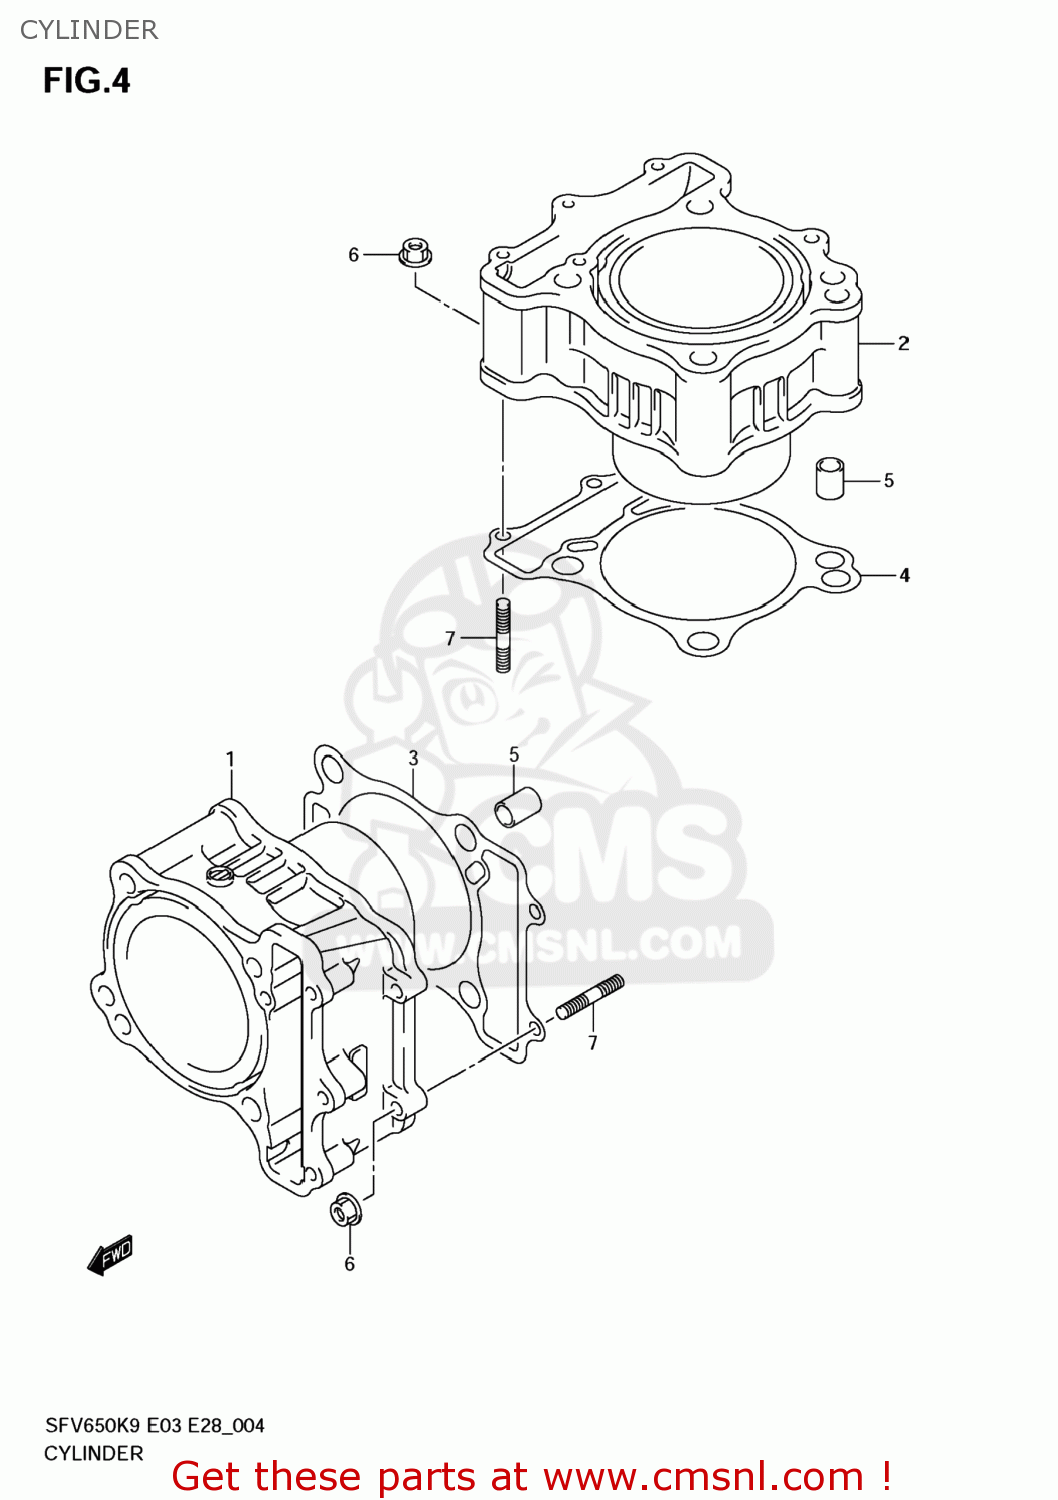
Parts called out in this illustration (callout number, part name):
1	CYLINDER,FR
2	CYLINDER,RR
3	GASKET,CYLINDER FR (NAS)
4	GASKET,CYLINDER RR (NAS)
5	PIN
6	NUT
7	BOLT,STUD
